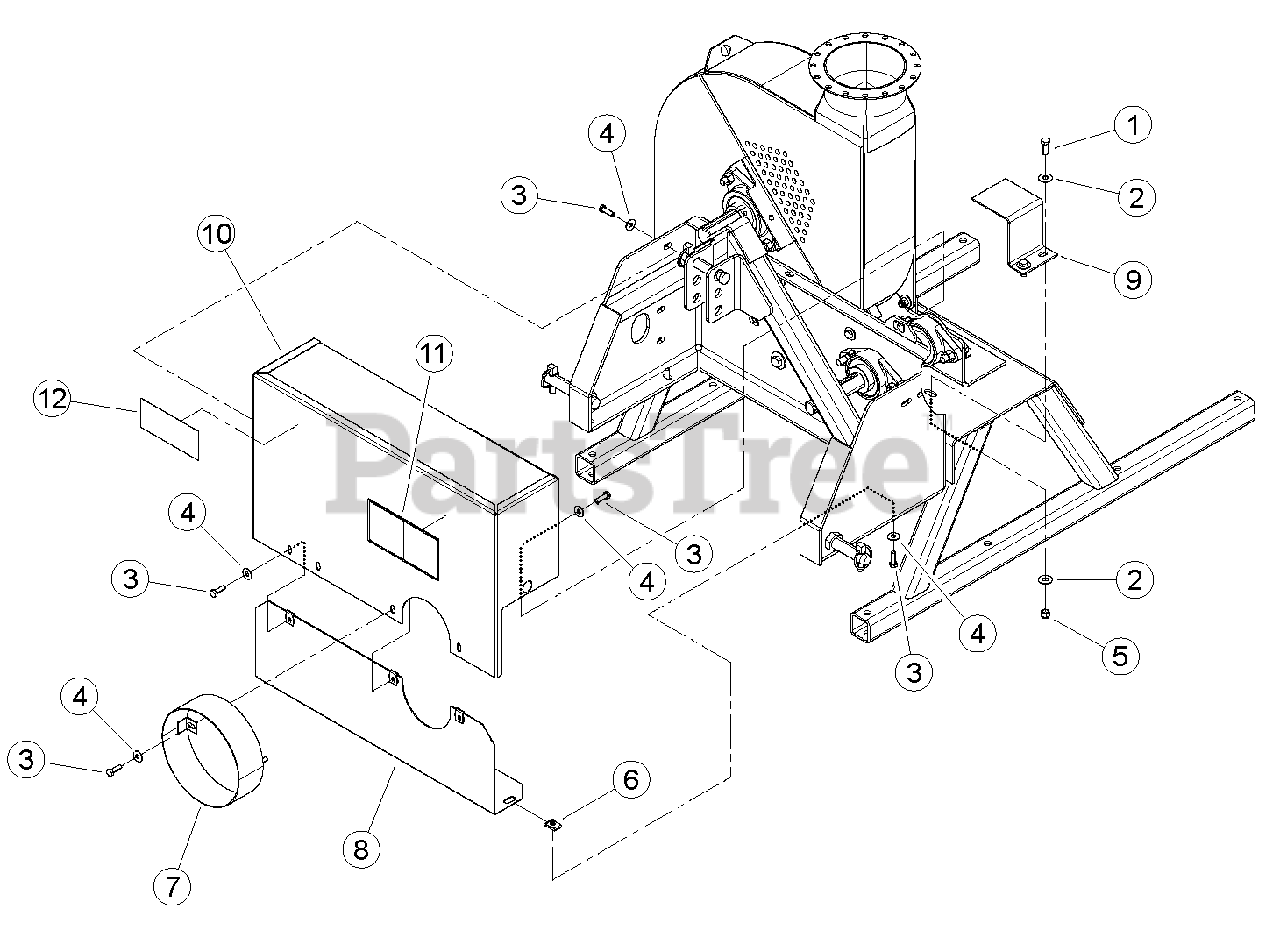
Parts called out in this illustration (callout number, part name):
1	BOLT, 3/8 X 1 HEX HD GR5 ZP
2	WASHER, 3/8 FLAT ZP
3	BOLT, 5/16 X 1 HHCS GR5 NC ZP
4	WASHER, 5/16 FLAT ZP
5	NUT, 3/8 NE NYLOCK ZP
6	NUT, 5/16-18 TINNERMAN U-TYPE
7	WELDMENT, JOINT SHIELD
8	GUARD, LOWER BELT
9	COVER, JACKSHAFT
10	ASSEMBLY, BELT SHIELD SERVICE PART
11	DECAL, PTO DANGER ISO
12	DECAL, MUTILINGUAL MANUAL
